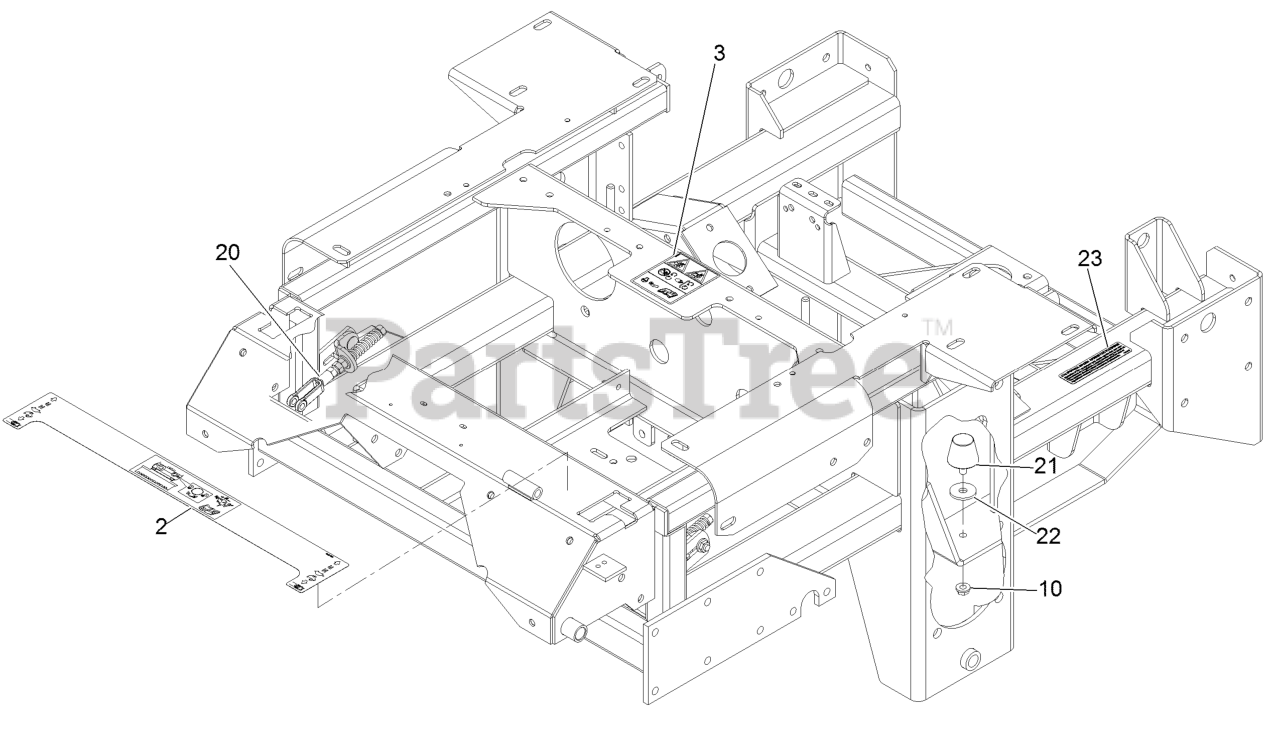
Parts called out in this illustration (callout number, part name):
2	Decal-Console Center
3	Decal-Rotating Device Hazard
20	NEUTRAL RETURN ASM
21	BUMPER-RUBBER
23	DECAL-ARRESTER, SPARK
